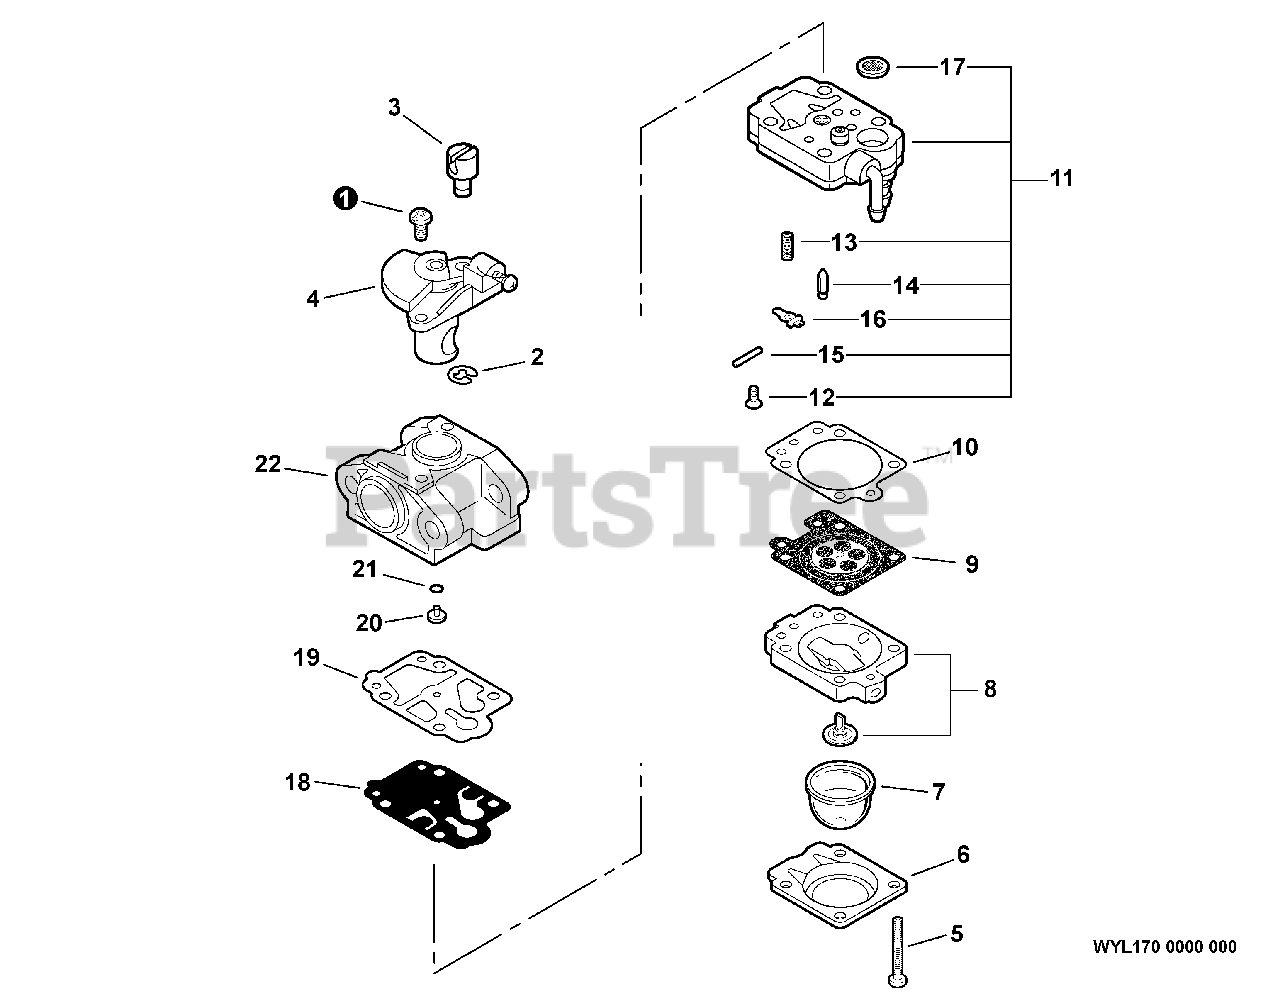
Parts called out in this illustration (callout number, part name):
1	SCREW, THROTTLE COLLAR
4	VALVE ASSY, THROTTLE
6	RETAINER, PURGE BULB
7	BULB, PURGE
8	BODY ASSY, PURGE
9	DIAPHRAGM, METERING
10	GASKET, METERING DIAPHRAGM
11	BODY ASSY, PUMP
12	SCREW, METERING LEVER PIN
13	SPRING, METERING LEVER
14	VALVE, INLET NEEDLE
15	PIN, METERING LEVER
16	LEVER, METERING
17	STRAINER
18	DIAPHRAGM, FUEL PUMP
19	GASKET, PUMP
20	JET, MAIN #37
22	BODY, CARBURETOR
